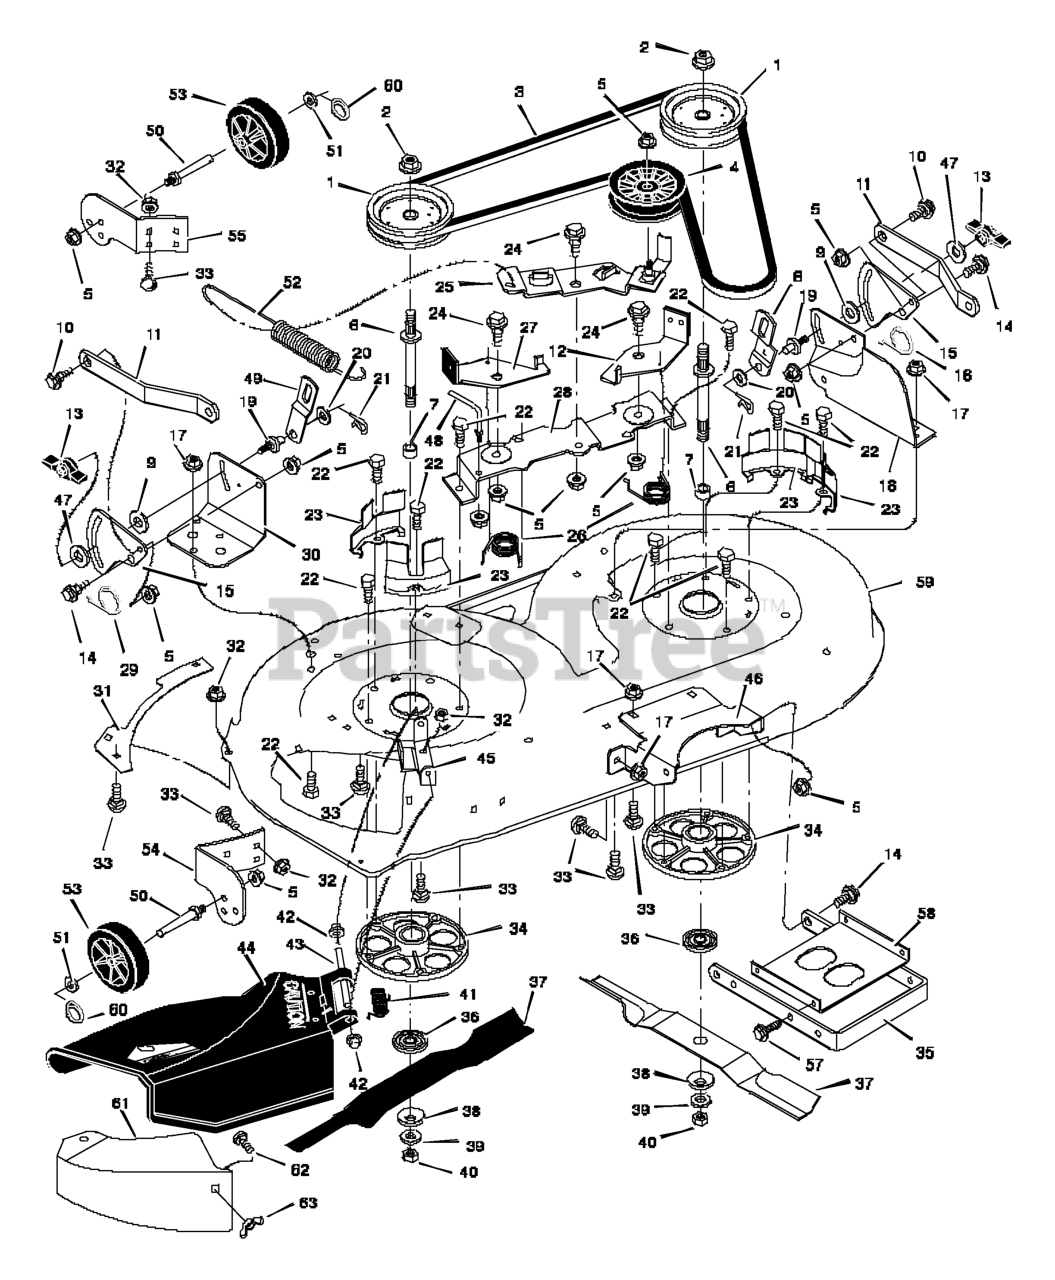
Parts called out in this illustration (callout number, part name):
1	Pulley, Jackshaft
2	Nut, Hex
3	Belt, Mower Drive
4	Pulley, Idler
5	Nut, Flange
6	Jackshaft
8	Link, Left Lift
9	Pad, Friction
10	Bolt, Shoulder
11	Bracket, Suspension
12	Pad Assembly, Left Brake
13	Knob
14	Bolt, Shoulder
15	Plate, Suspension
17	Nut, Flange
18	Bracket, Suspension
19	Pin, Hanger
21	Pin, Hair
22	Bolt
23	Cover, Pulley
24	Bolt, Shoulder
25	Arm, Idler
27	Pad Assembly, Right Brake
28	Bracket, Brake
30	Bracket, Suspension
32	Nut, Flange
33	Bolt, Carriage
34	Mandrell Housing
35	Bracket, Suspension
36	Adapter, Blade
42	Cap, Push On
43	Rod, Pivot
44	Deflector
45	Bracket, Deflector Hinge
46	Bracket, Front Hanger
48	Guide, Belt
49	Link, Right Lift
50	BOLT, Gauge Wheel
52	Spring, Extension
53	Wheel, Gage
54	Bracket, Right Wheel
55	Bracket, Left Wheel
56	Brace, Hanger
58	Stiffener
59	Housing, Blade
60	Ring, Locking
61	Cover, Mulcher
62	Bolt, Carriage
63	Wingnut
